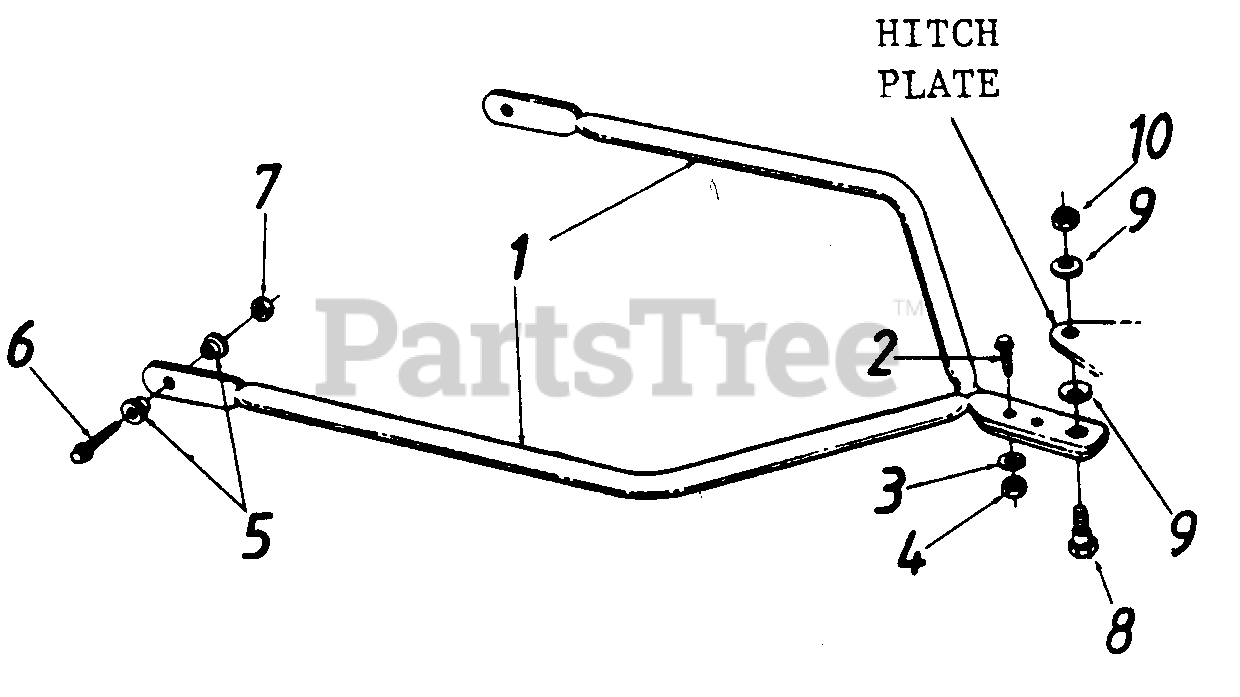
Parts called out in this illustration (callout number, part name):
3	L.Wash. 1/4" I.D.
4	Hex Nut 1/4-20 Thd.
5	Shoulder Spacer
6	Hex Wash. Hd. Self-Tapp Scr. 5/16-18 x 1.0" 4.
7	Hex Nut 5/16-18 Thd.
8	Shoulder Bolt
9	Bell-Wash. .39" I.D. x 1.12" O.D
10	Hex Top Jam Nut 3/8-16 Thd.
